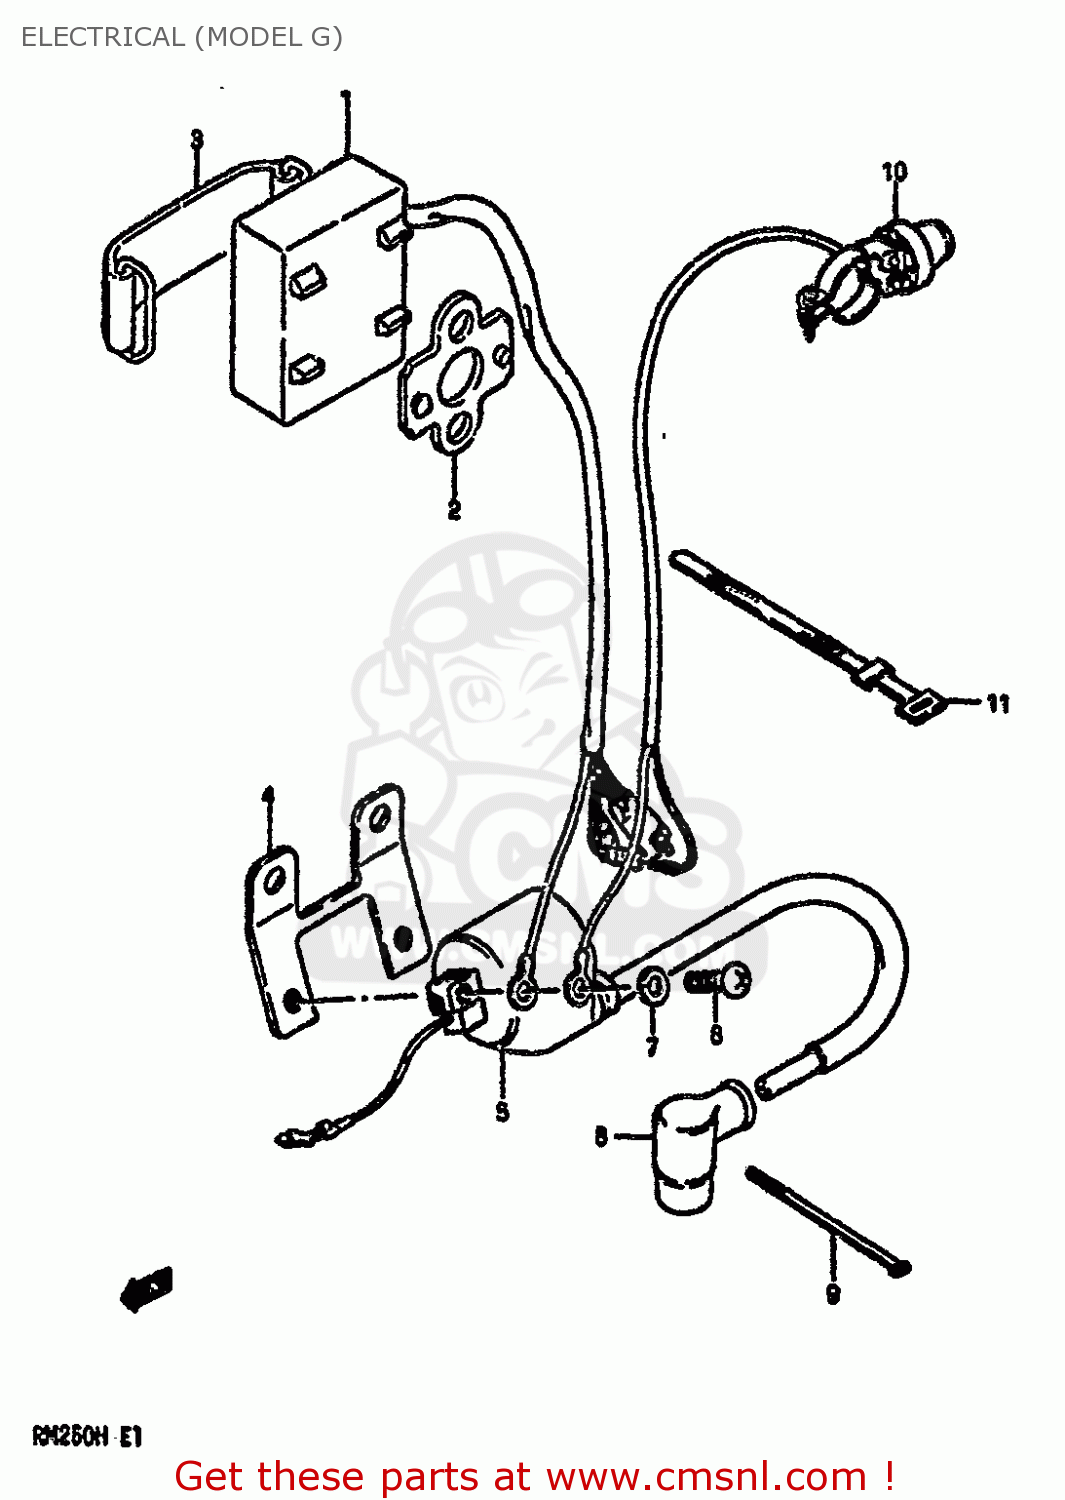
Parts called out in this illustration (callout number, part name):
1	UNIT ASSY,CDI
2	PROTECTOR,CDI UNIT
3	BAND
4	BRACKET,IGNITION COIL
5	COIL ASSEMBLY,IGNITION
6	SCREW
7	WASHER,LOCK
8	CAP,SPARK PLUG
9	CLAMP
10	SWITCH ASSEMBLY
11	CLAMP(L:120)
